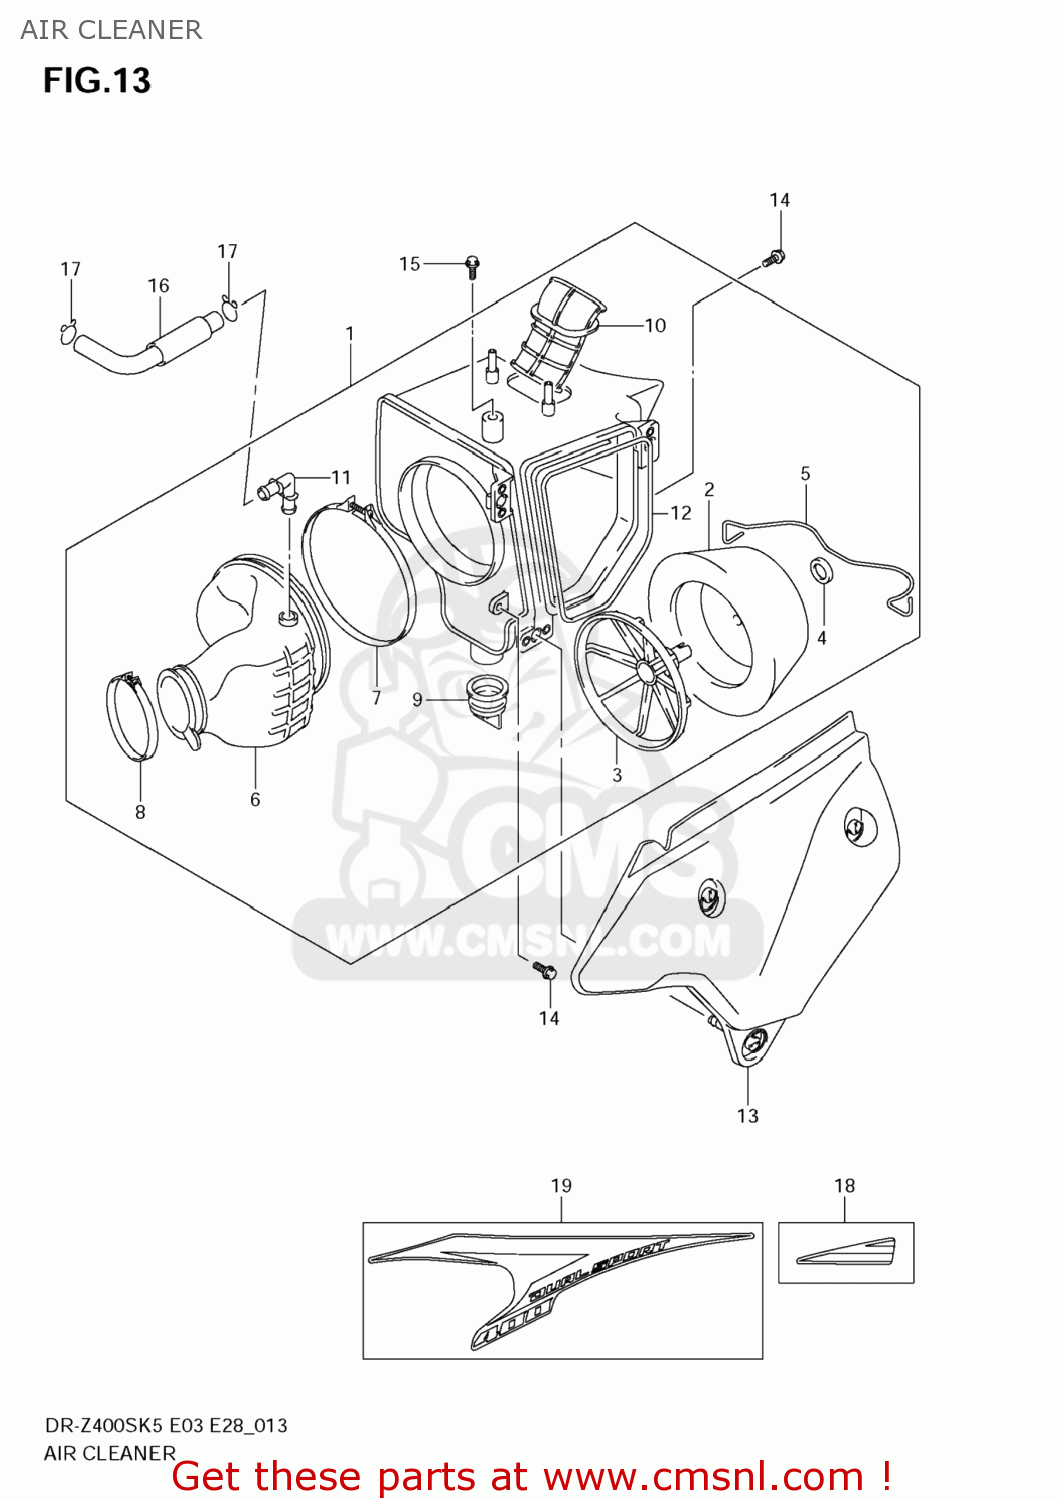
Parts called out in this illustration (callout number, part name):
1	CLEANER,AIR
2	FILTER ASSY
3	HOLDER,FILTER
4	SPACER
5	SPRING
6	TUBE,OUTLET
7	CLAMP
8	CLAMP
9	VALVE
10	TUBE,INLET
11	JOINT
12	GASKET,AIR CLEANER (NAS)
13	CAP,AIR CLEANER
14	BOLT
15	BOLT(6X14.6)
16	TUBE,BREATHER
17	CLIP
18	TAPE,AIR CLNR CAP
19	TAPE,AIR CLNR CAP
